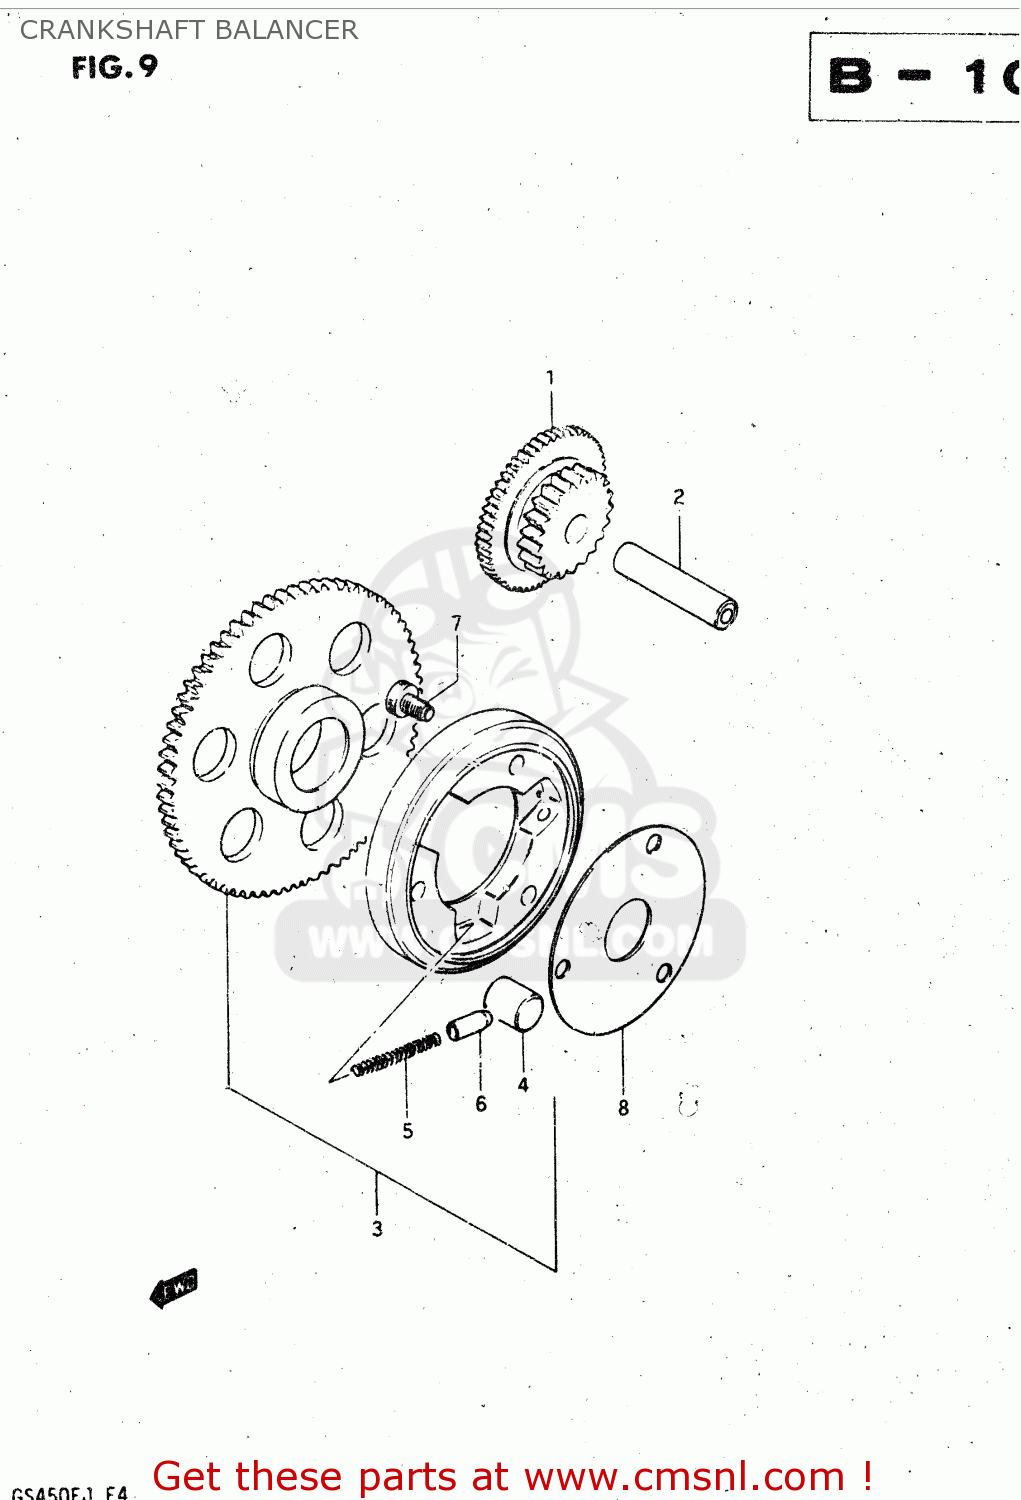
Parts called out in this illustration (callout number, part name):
1	BALANCER,CRANKSHAFT
2	GEAR,CRANK BALANCER DRIVE
3	WASHER
4	SPRING
5	PIN
6	SPACER
7	WASHER(12X50X3)
8	BOLT
9	METAL CRANKSHAFT
